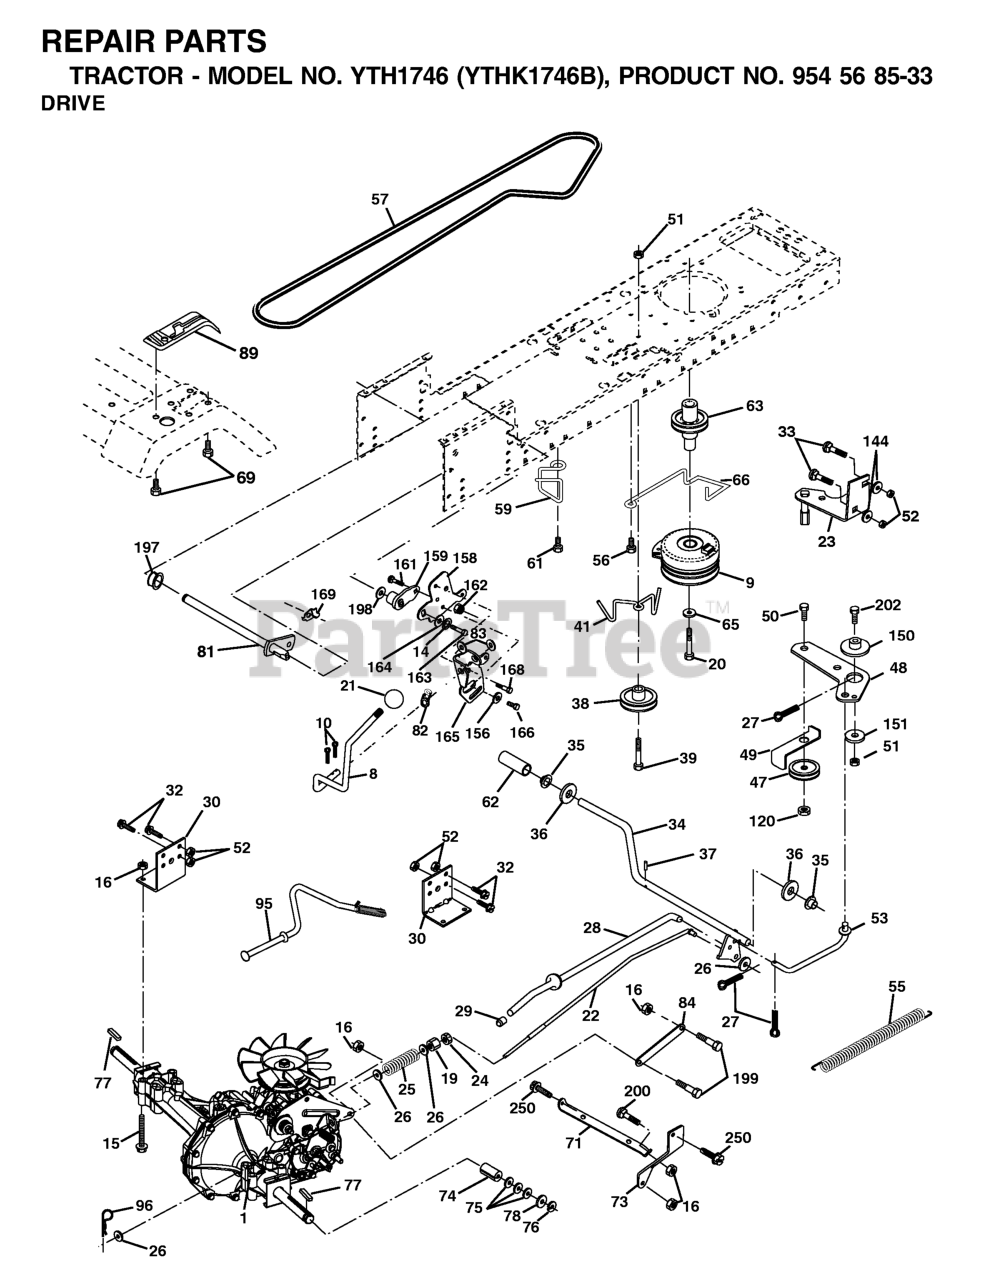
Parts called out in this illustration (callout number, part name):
1	DECK.WELDMENT.42"
6	ARM.SUSPENSION.MOWER.R
8	BOLT.WASHER.ASM.7/16-2
11	42" HI-LIFT BLADE
13	SHAFT.ASM.MDRL.N/GREASE.38
14	RP.HOUSING.MANDREL.4PT.
16	STRIPPER.MANDREL.ROUND.BLACK
19	BOLT.SHOULDER
20	BAFFLE.VORTEX
21	LOCKNUT
23	BRKT.DEFLECTOR.38"2005+
24	CAP-SLEEVE LT
25	SPRING.TORSION.DEFLECT
26	NUT PUSH M
27	SHIELD.DEFLECTOR.MOWER.42"BLAC
29	ROD.HINGE
30	SCREW, WASHER HEAD
31	WASHER.SPACER.MANDREL
32	PULLEY/MANDREL
33	NUT.FLANGE.LOCK.TOP
34	BOLT.3/8-16X1.50
36	PULLEY.IDLER.2006
40	NUT LOCK FLG 3/8-16 UNC
56	SPACER.RETAINER
57	SCREW 3/8-16X1
59	GUARD, BELT
68	BELT V SECONDARY
69	BOLT
116	BOLT M
117	WHEEL.GAGE.HALF.SPOKED
119	WASHER
145	PULLEY.IDLER.48"PRIMARY
188	STUD.FASTNER.W/ANTI-ROTATE
189	NUT LOCK HEX FLANGE 5/16-18
190	SPRING.MOWER.DRIVE.ELECTRIC
